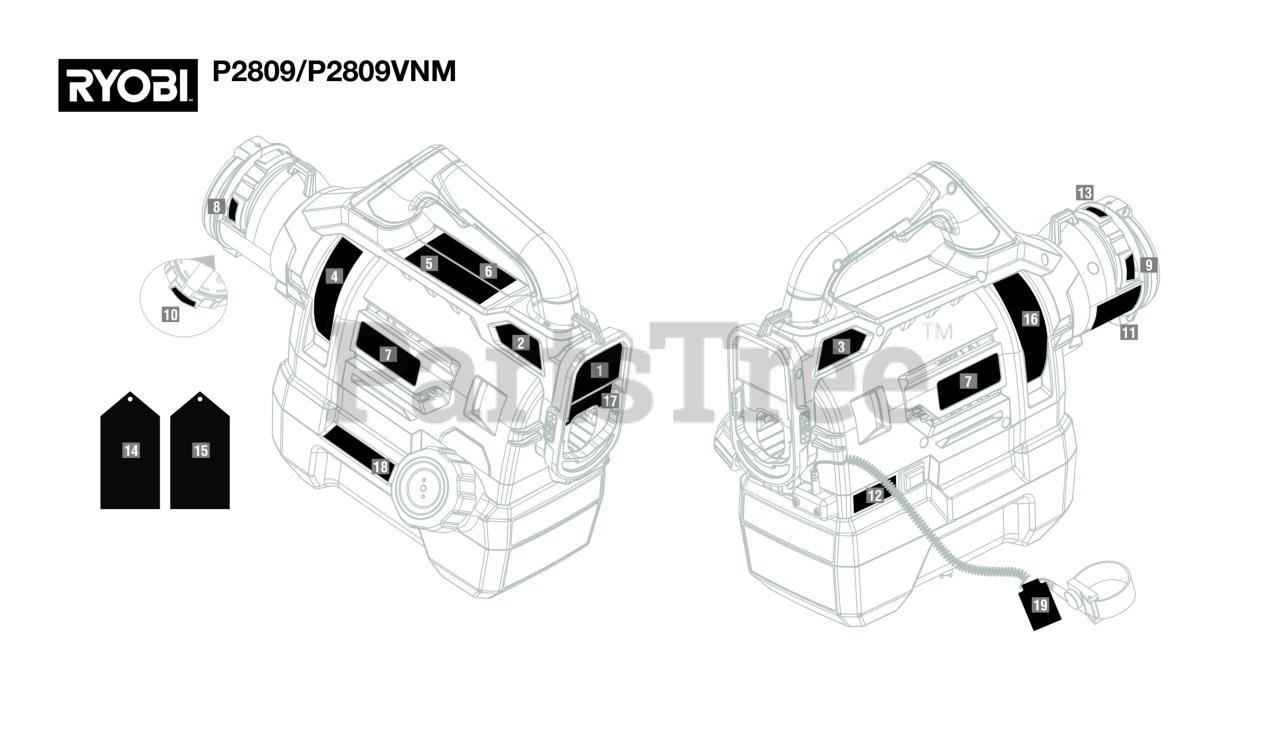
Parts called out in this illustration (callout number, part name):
1	Data Label (Foot)
2	18V Label (Left)
3	18V Label (Right)
4	Electrostatic Logo Label (Left)
5	Warning/Icon Label
6	Warning Label
7	Logo Label
8	High Spray Nozzle Label
9	Low Spray Nozzle Label
10	Medium Spray Nozzle Label
11	Caution Label
12	ES On/Off Label
13	Remove/Eject Puck Label
14	Cleaning Nozzle Reference Guide Hang Tag (EN/FR/SP)
15	Cleaning Nozzle Reference Guide Hang Tag (PORT)
16	Electrostatic Logo Label (Right)
17	Clean Tank and Lines Label
18	Max Fill Label
19	Anti-Static Cord Wrap
